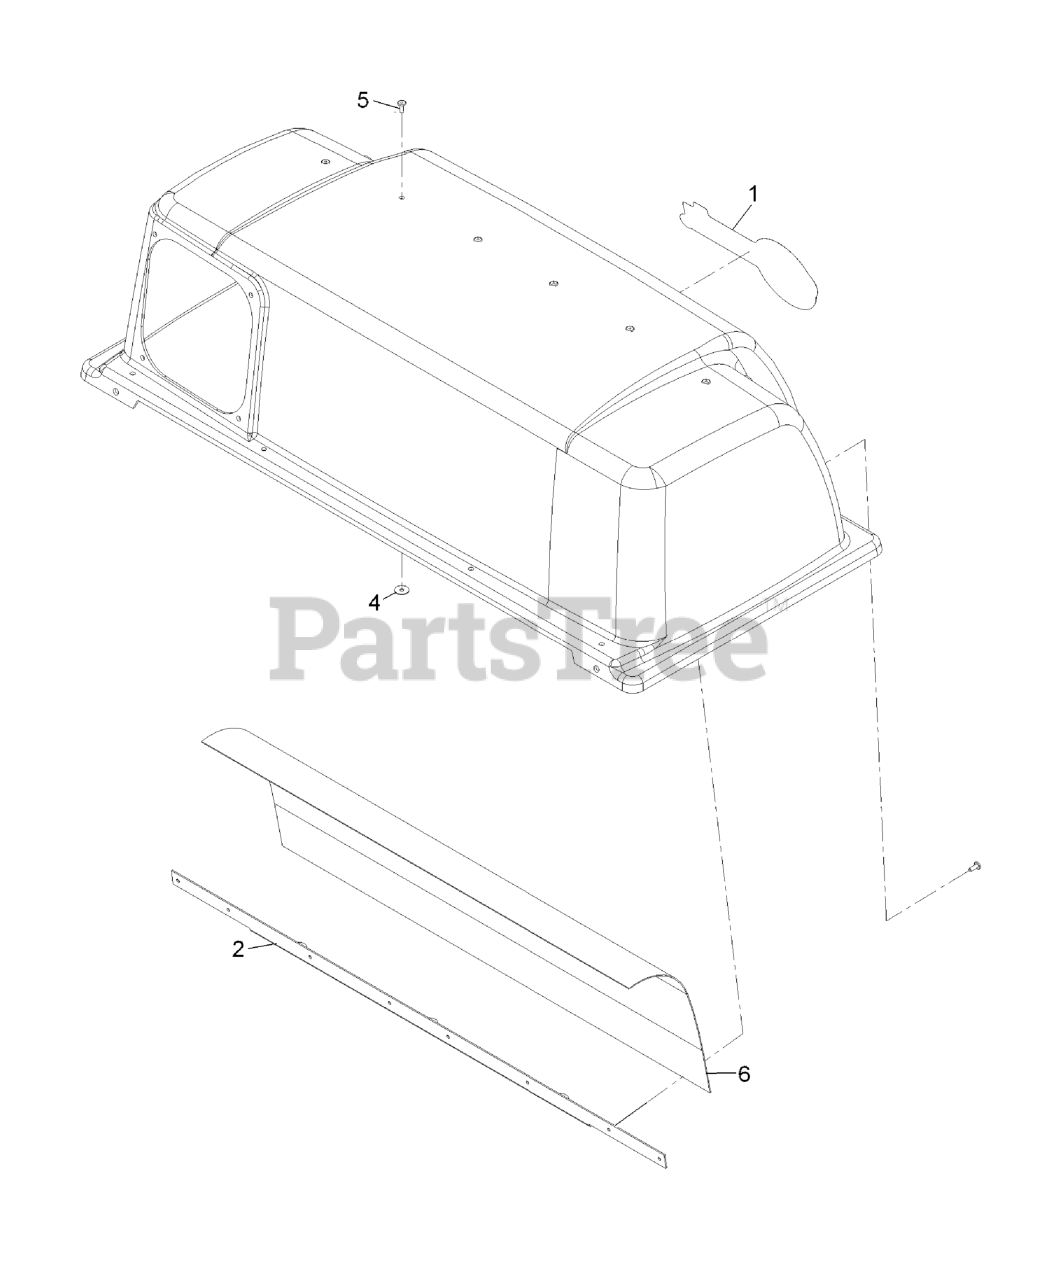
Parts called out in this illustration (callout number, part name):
1	DECAL-EXMARK LOGO
2	SUPPORT-SCREEN
4	WASHER-FLAT
5	RIVET-BLIND
6	SCREEN-BAGGER
